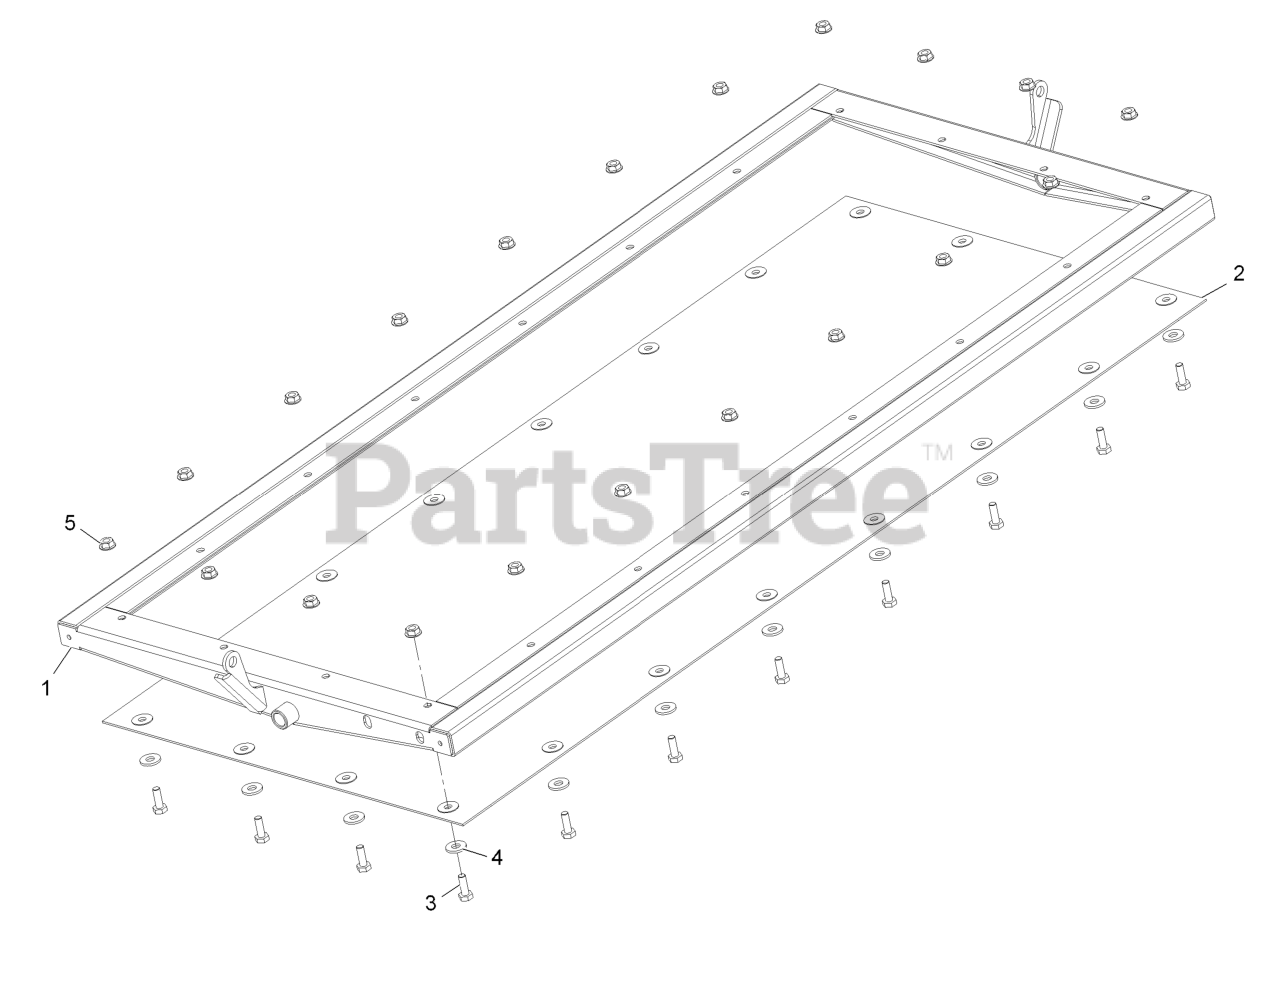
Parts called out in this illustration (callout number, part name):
1	Door-Frame
2	Screen-Door
3	Screw-HH 1/4-20 X 3/4
4	Washer-1/4 Std
5	Nut-Whizlock 1/4-20
